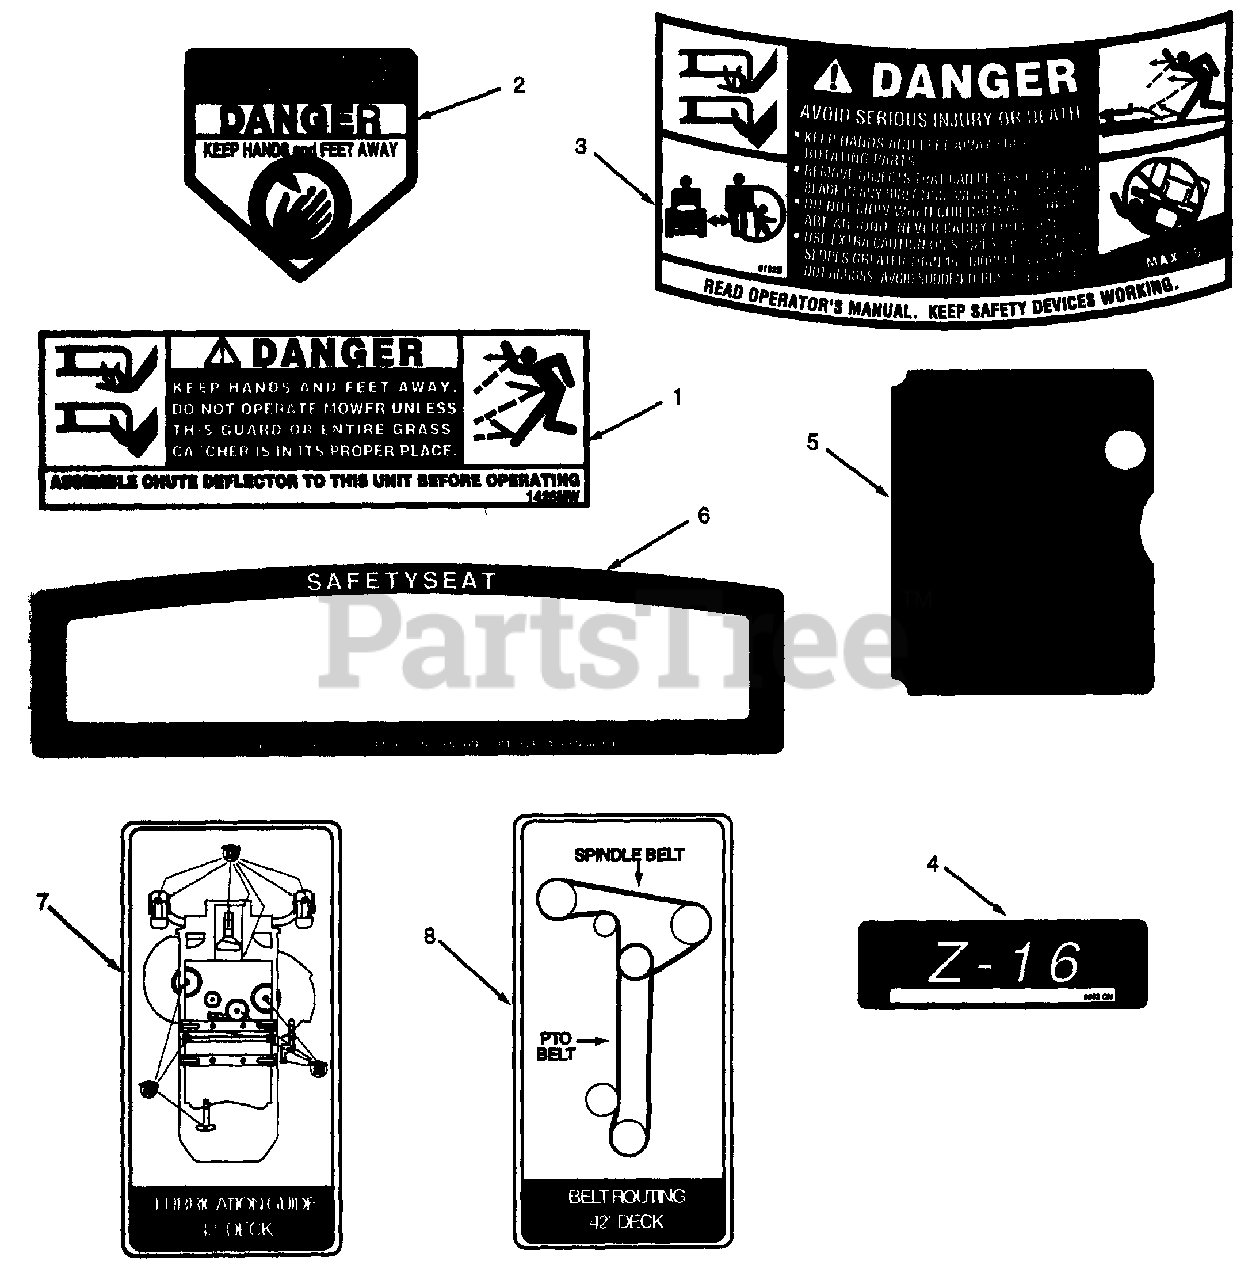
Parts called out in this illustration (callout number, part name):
1	Label, Danger - Top of Deck
2	Label, Danger - Top of Deflector Chute
3	Label, Safety - Top of Deck
4	Label, model - Front Steering Console
5	Label, Control Panel Cover- Hr/Tach
6	Label, Safety - Back of Seat
7	Label, Information - Under Belt Cover
8	Label, Information - Under Belt Cover
